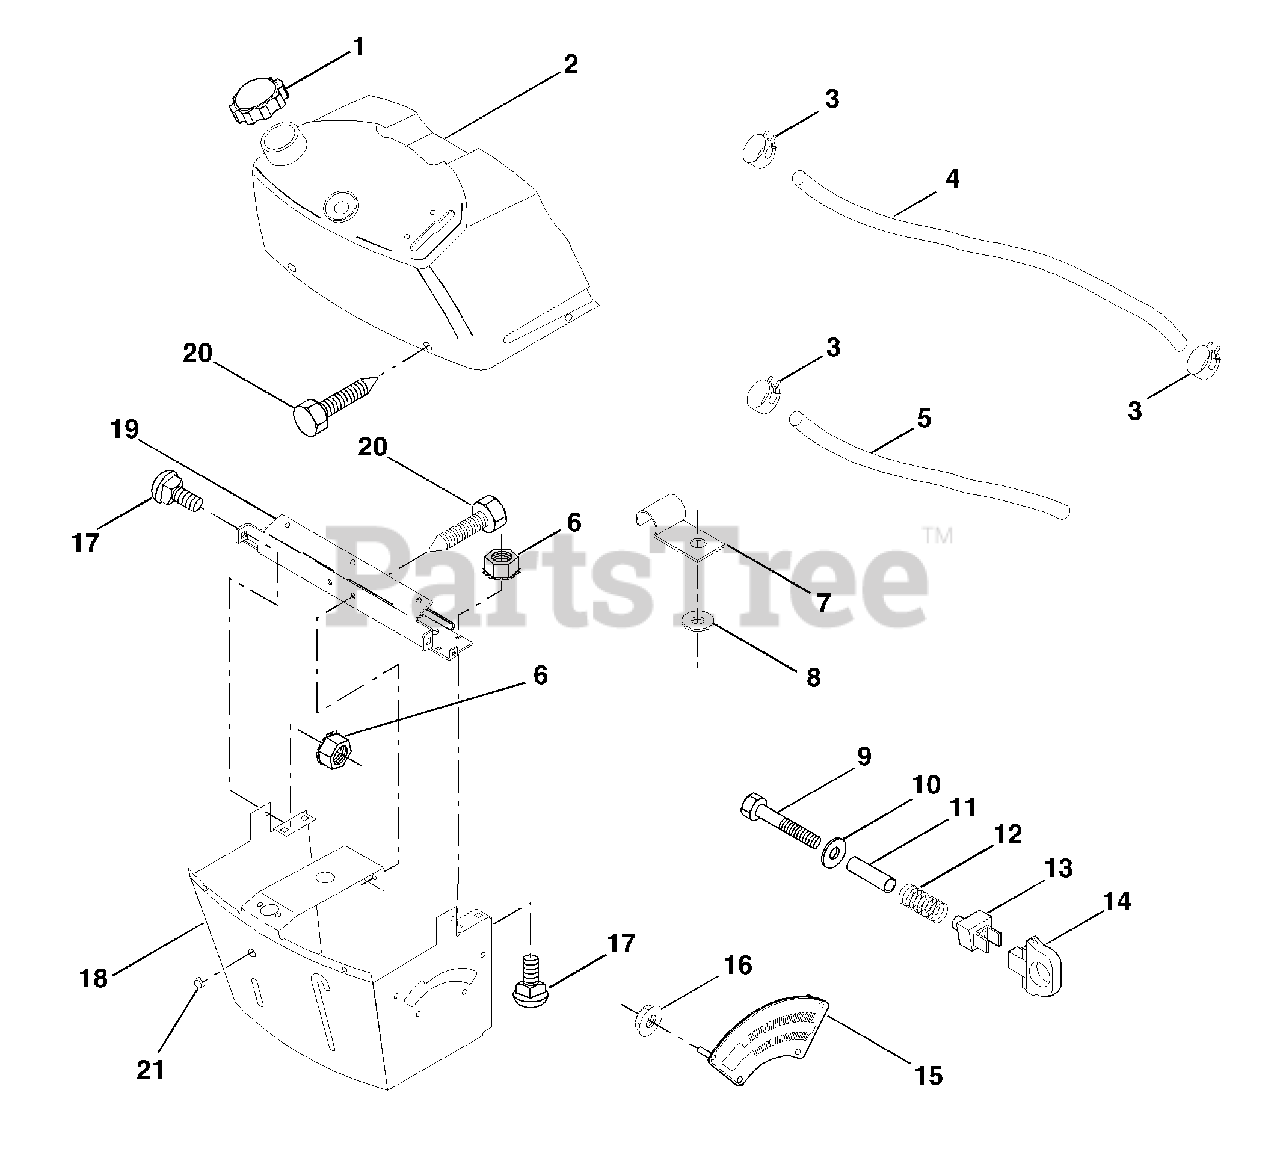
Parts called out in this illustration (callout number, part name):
2	Assembly, Dash & Fuel Tank
3	Clamp, Hose
4	Line, Fuel
5	Line, Fuel
6	Nut, Hex, Keps 1/4-20
7	Clip, Fuel Line
8	Washer 9/32 x 3/4 x 16 Ga.
9	Bolt, Hex, Fin 1/4-20 x 1-3/4
10	Washer 11/32 x 11/16 x 16 Ga.
11	Spacer, Split
13	Clip, Height Adjustment
14	Knob, Height Stop
15	Adjustment, Quadrant Height
16	Nut, Self-Threading 3/16-18
17	Bolt, Carriage 1/4-20 x 1/2 Gr. 5
18	Support, Assembly Dash
19	Brace, Cross
20	Screw, Self-Tapping 1/4-20 x 1/2
21	Plug, Dome Black
